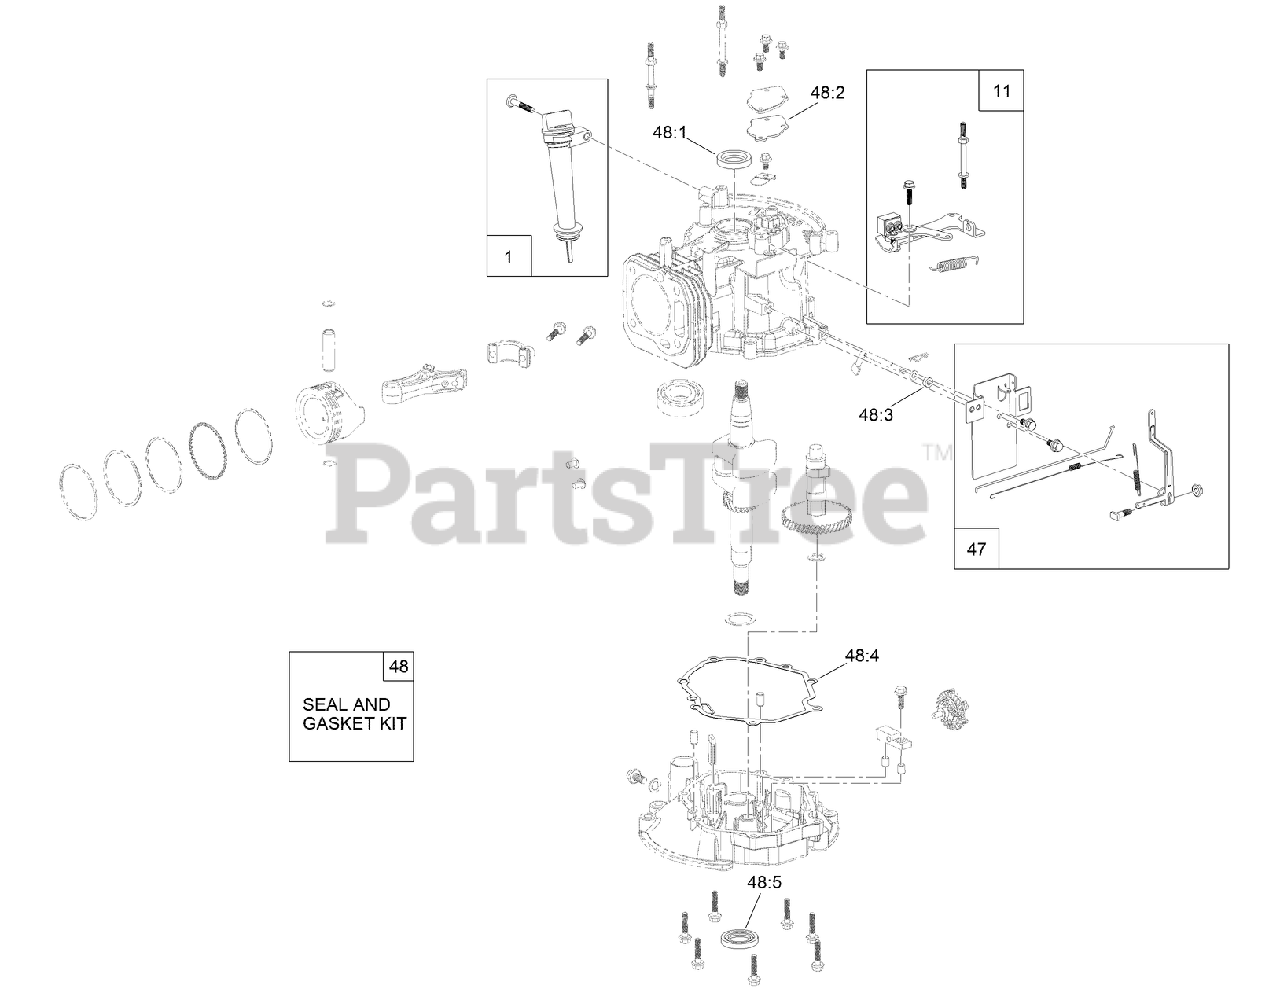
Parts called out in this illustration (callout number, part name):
1	DIPSTICK AND FILL TUBE KIT
11	BRAKE ASM RECOIL KIT
47	GOVERNOR ARM KIT
48	SEAL AND GASKET KIT
48:1	SEAL-OIL
48:2	GASKET-BREATHER
48:3	SEAL-OIL
48:4	GASKET-COVER, CASE
48:5	SEAL-OIL
